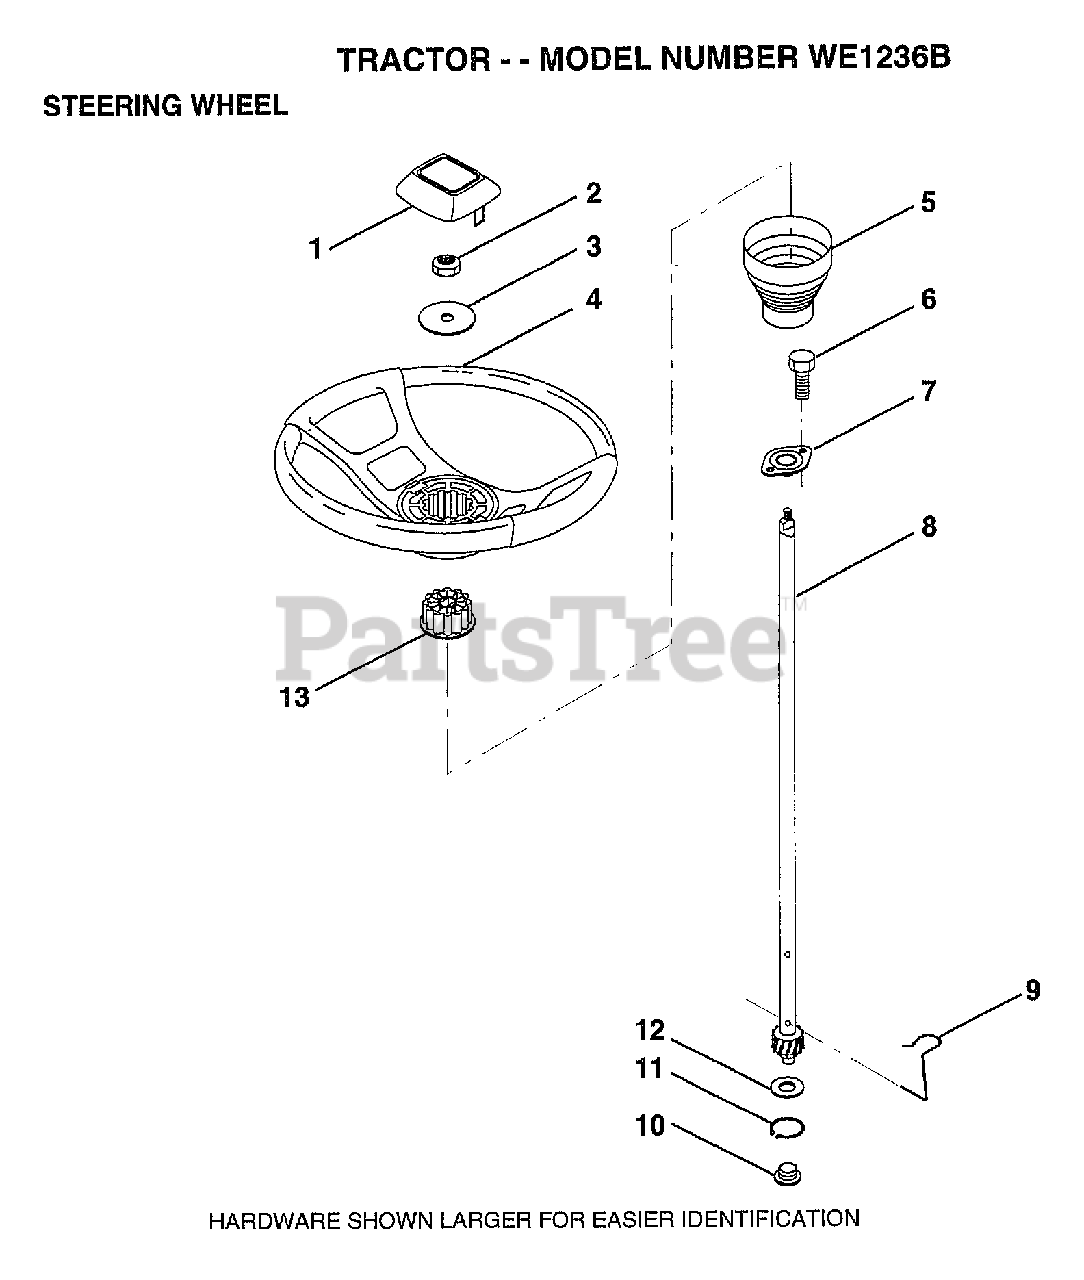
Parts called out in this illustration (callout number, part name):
1	ST WHL INSERT CAP
2	GRIPCO NUT
3	WASHER T
5	SLEEVE STEERING
9	STEERING CLIP
10	BUSHING STEER LWR
11	RING
12	WASHER LT
13	ADAPTER-WHEEL LT
